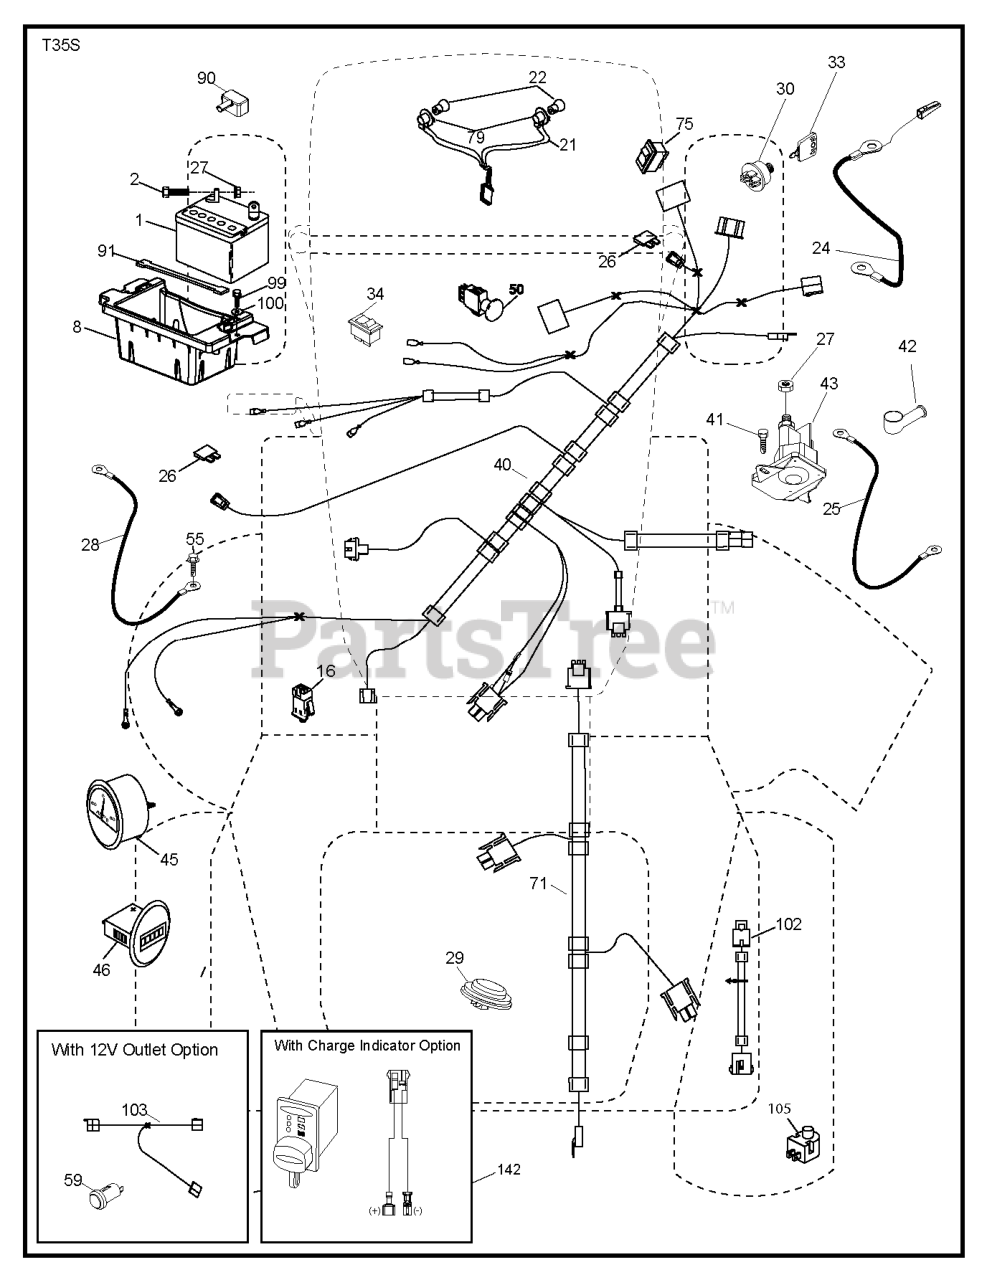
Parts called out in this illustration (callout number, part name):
1	Battery, Dry 30 Amp
2	BOLT.HEX.1/4.X.3/4.DICHROMATE
8	BOX BATTERY FULLY ASSEMBLED
16	SWITCH INTERLOOK PUSH-IN
21	HARNESS.LIGHT W/4152J BULBS
24	CABLE.BATT.POS.WIRE.TG.DA SOL
25	CABLE.STARTER.6G.BL/RED.17.5
26	FUSE 20AMP
27	NUT
28	CABLE GROUND 6 GA 21" 90T BLK
29	SWITCH.SEAT.DELTA.OPC.
30	SWITCH.IGN.DELTA.W.LGH.ROS
33	KEY.CHAIN.BLISTER.PACK.GEN.USA
40	HARNESS.DASH.EDIFF.RND.CHR.EF
41	SCREW
42	TERMINAL COVER
43	SOLENOID.W/BRASS.PLUNGER
45	AMMETER GAUGE ROUND SNAP-IN
46	HOURMETER.GAUGE.RNK.SNAP.LS
50	RP.PTO.SWITCH.8 TERMINAL.BLACK
55	SCREW 5/16"
59	OUTLET.12-VOLT
71	HARNESS.IGN.CHASSIS.TEX.DCKLOC
75	SWITCH.ON/OFF.(DIFF.LOCK)
79	BULB HOLDER ASM.
90	COVER.TERMINAL.BATTERY
91	STRAP.BATTERY.MOUNT.FRONT(2 2)
99	SCREW HEXWSHR 1/4-20X3/4
100	WASHER
102	HARNESS PIGTAIL PCH TEX ROS
103	HARNESS.PIGTAIL.12V.OUTLET.
105	REVERSE SWITCH
142	RP HARNESS.CHASSIS.TEX.8AWG
